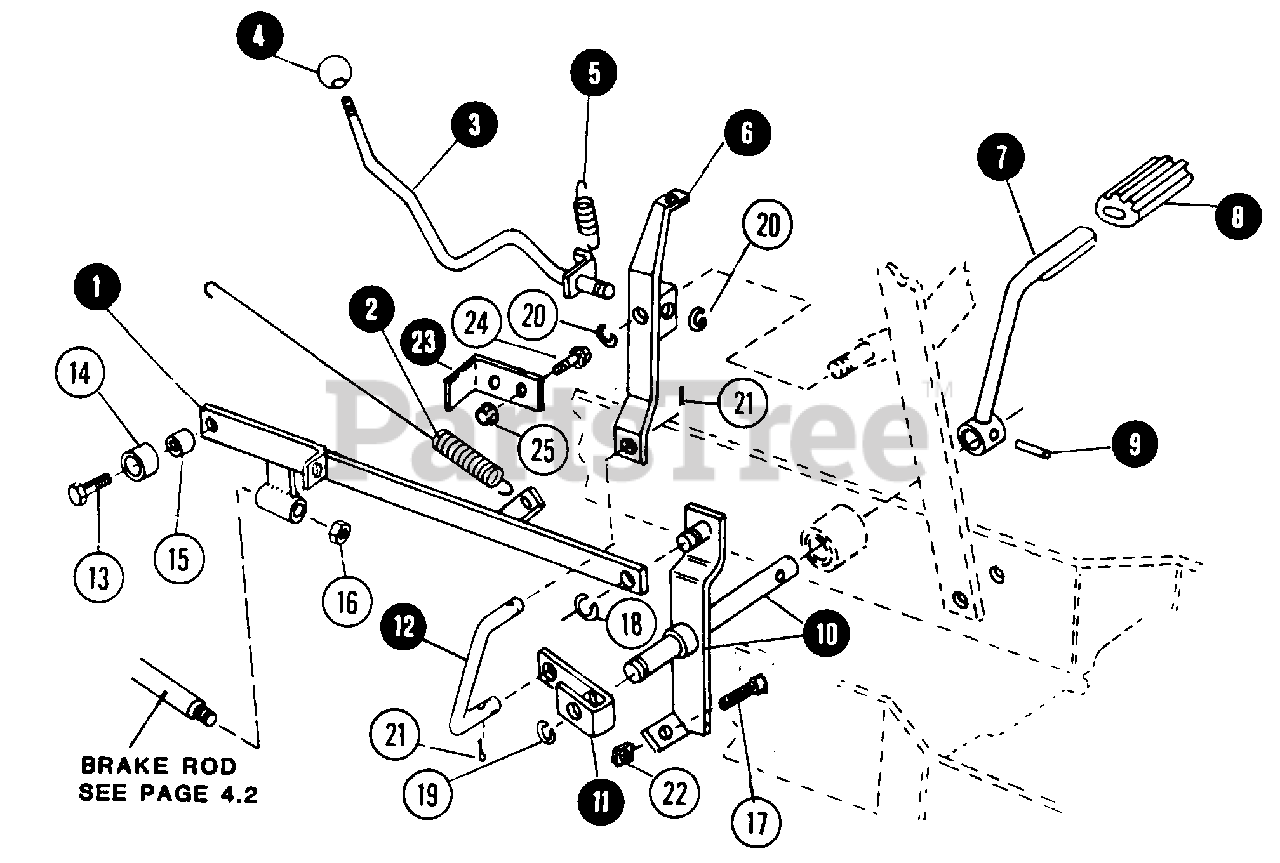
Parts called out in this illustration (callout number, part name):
1	STRAP BRAKE AND SELECTOR - ASSEMBLY
2	SPRING, STRAP RETURN
3	LEVER, SPEED SELECTOR SHIFT
4	KNOB, SHIFT LEVER
5	SPRING, SELECTOR LEVER TENSION
6	LEVER, SELECTOR
7	PEDAL, PARKING BRAKE
8	PAD, PEDAL
9	PIN, GROOVE (1/4 x 1-1/4)
10	SHAFT, PEDAL
11	LINK, PEDAL SHAFT SELECTOR
12	LINK, SELECTOR
13	BOLT, 1/4C x 3/4 HEX HEAD
14	ROLLER, NEUTRAL RETURN
15	SPACER, STEEL
16	NUT, 5/16C HEX LOCK
17	SCREW, SELECTOR LINK ADJUSTER
18	RING, RETAINING
19	RING, RETAINING
20	RING, RETAINING
21	COTTER-PIN, 1/8 x 3/4
22	NUT, 5/16C MACHINE SCREW
23	ACTIVATOR, SHIFT INTERLOCK SWITCH
24	BOLT, 1/4-20 x 1/2 FLANGE LOCK
25	NUT, 1/4-20 FLANGE LOCK
